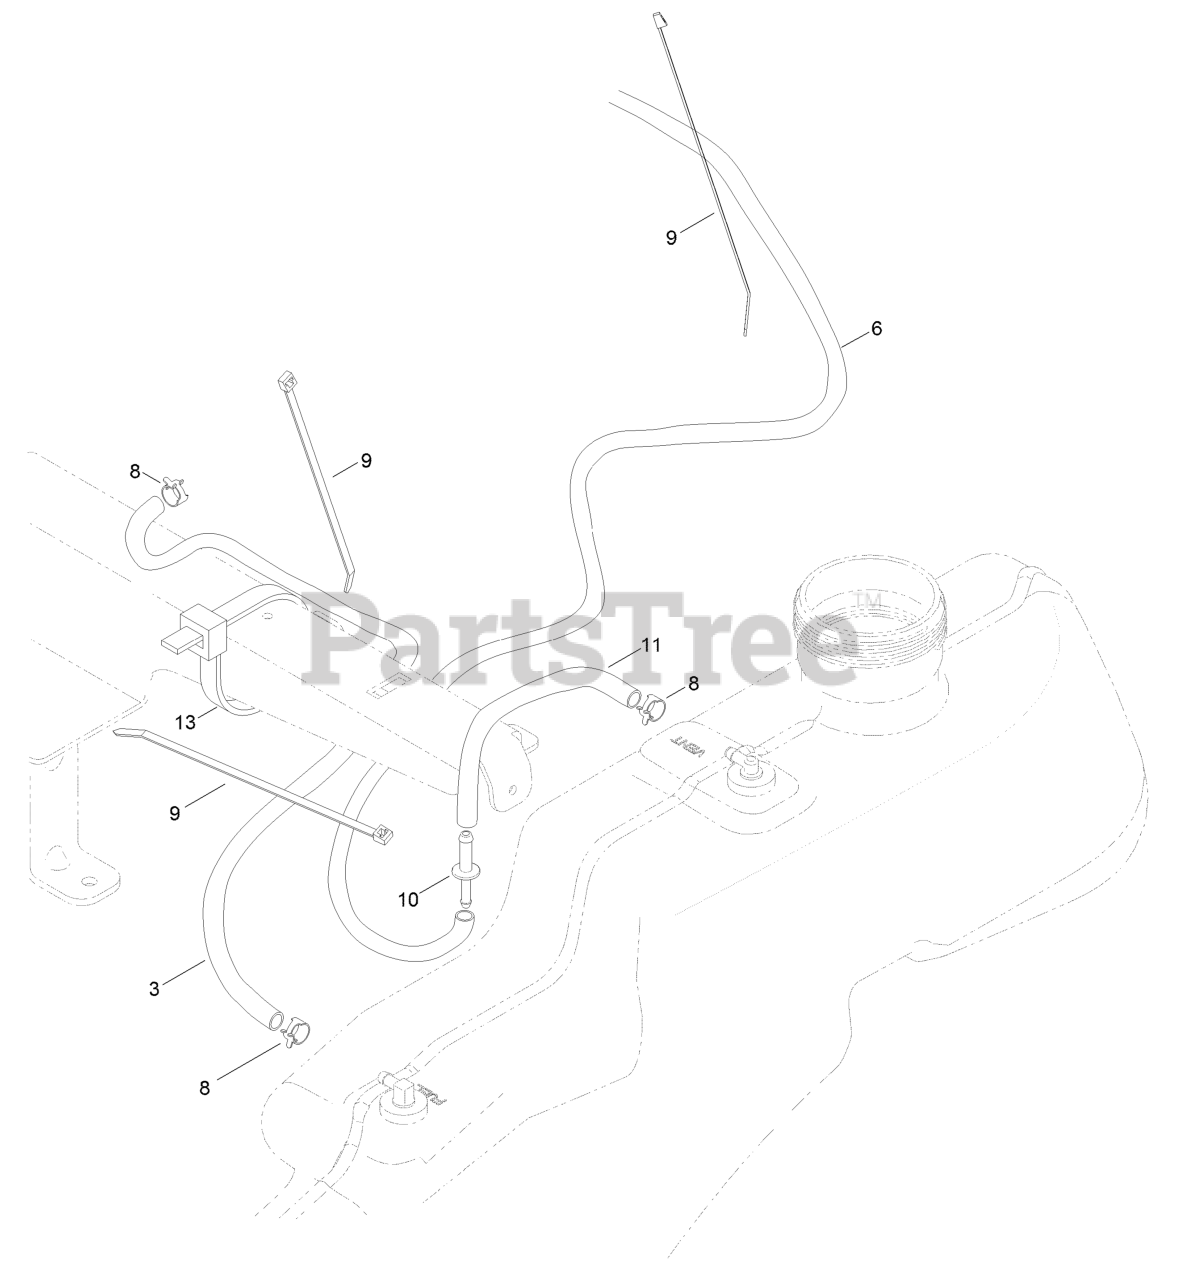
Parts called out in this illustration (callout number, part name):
3	HOSE-FUEL
6	HOSE-FUEL
8	CLAMP-HOSE
9	TIE-CABLE
10	ADAPTOR-ORIFICE
11	HOSE-FUEL
13	TIE-CABLE
